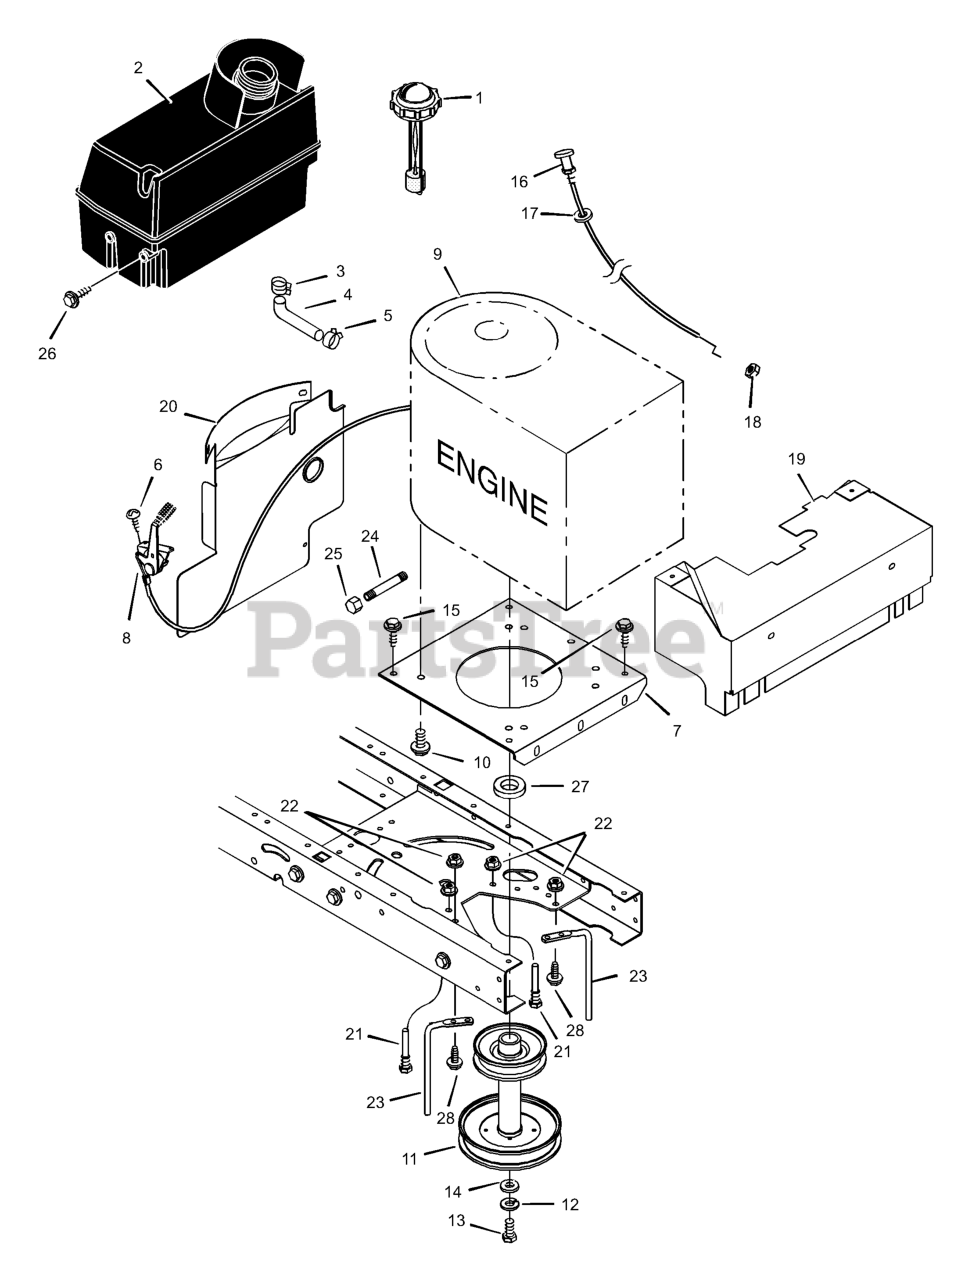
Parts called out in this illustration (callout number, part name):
1	Fuel Cap
2	Fuel Tank
3	Hose Clamp
4	Fuel Line
5	Hose Clamp
7	Plate, Engine
8	Throttle Control
9	Engine *
10	Bolt, Engine Mount
11	Stack Pulley Assembly
12	Lockwasher
13	Bolt, Hex
17	Washer
19	Baffle, Front Engine
20	Baffle, Rear Engine
21	Guide, Belt
22	Nut, Flange
23	Guide, "L" Belt
24	Pipe, Oil Drain
25	Cap, Oil Drain
28	Screw
